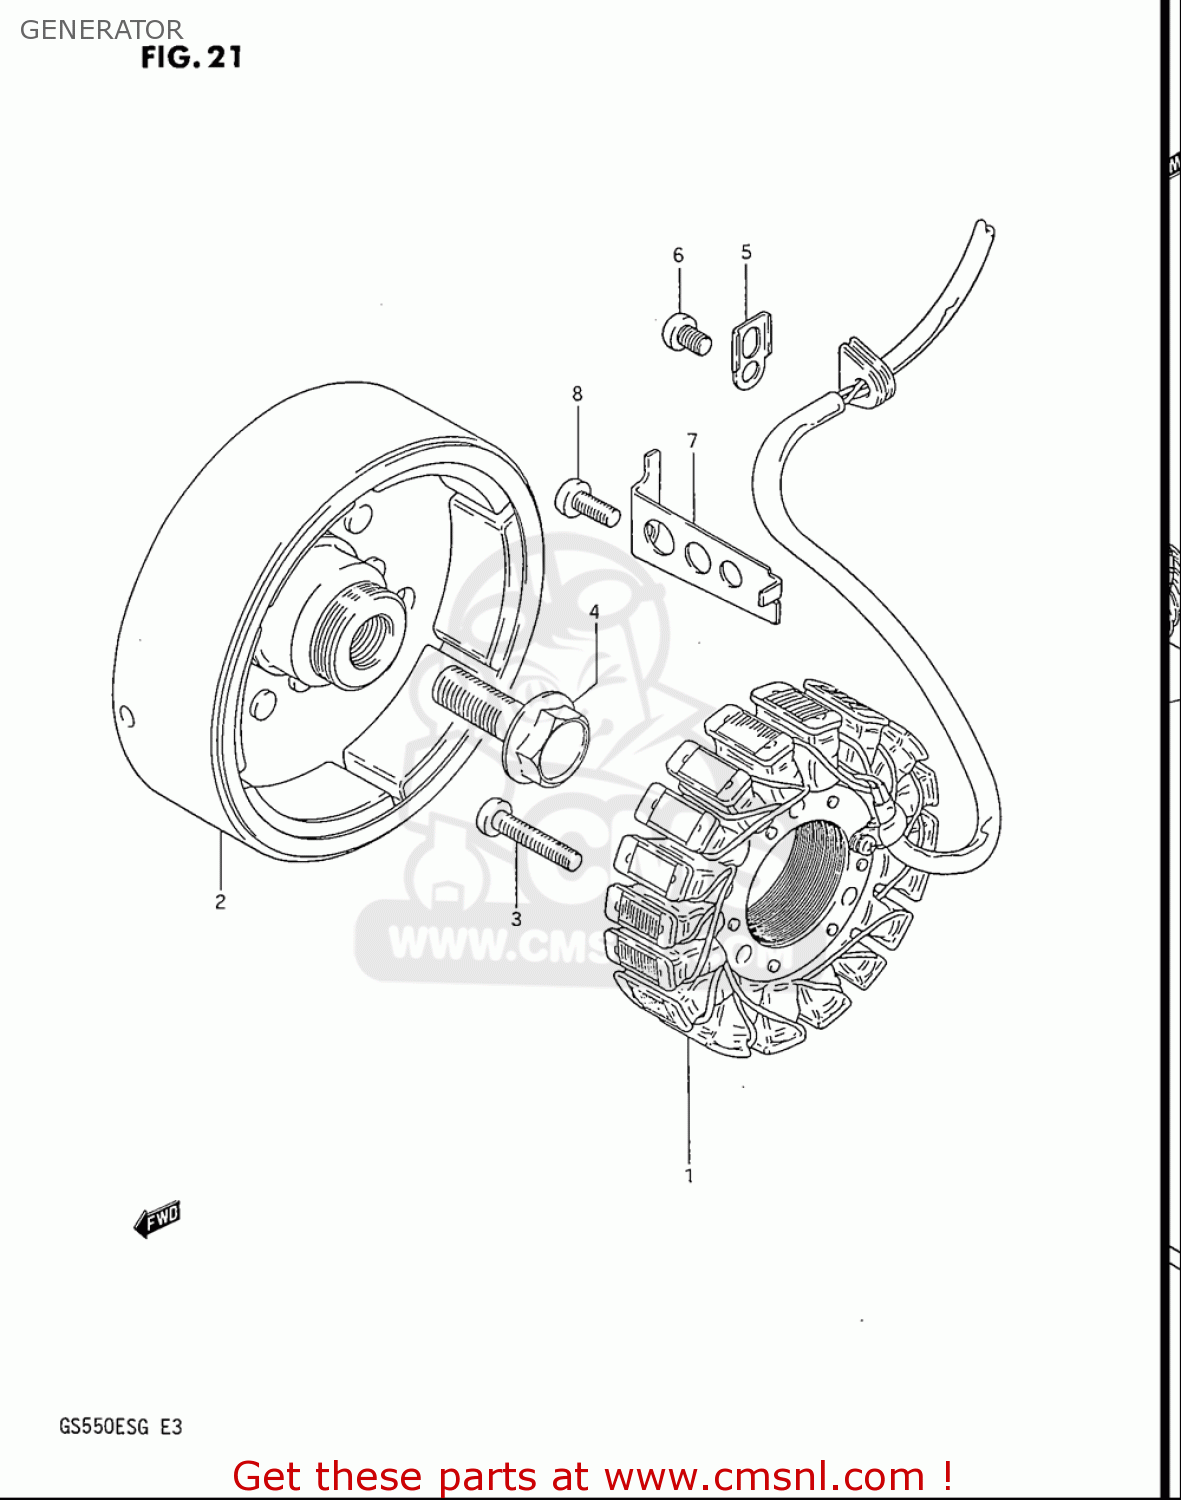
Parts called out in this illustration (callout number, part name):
1	STARTER ASSY
2	ROTOR ASSEMBLY
3	SCREW
4	BOLT(14X43)
5	CLAMP,GENERATOR LEAD WIRE
6	SCREW
7	CLAMP,GENERATOR LEAD WIRE
8	SCREW
